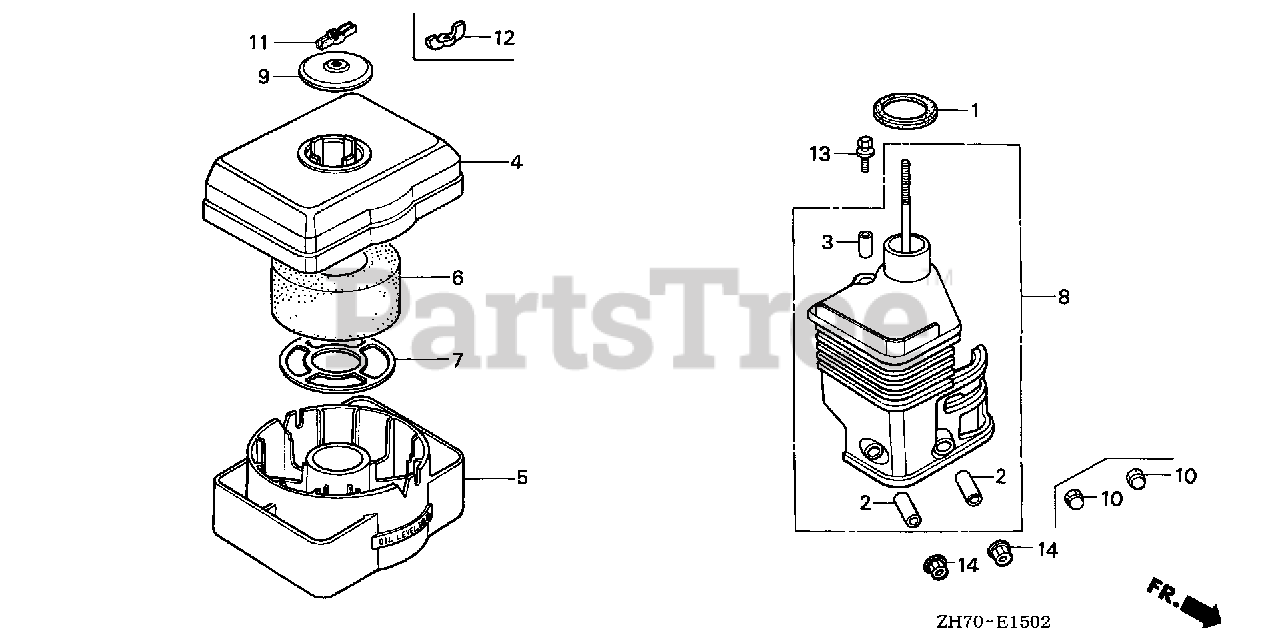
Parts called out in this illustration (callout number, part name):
1	GASKET, ELBOW
2	COLLAR, AIR CLEANER
3	COLLAR B, AIR CLEANER
4	BODY, CLEANER (OIL BATH)
5	PAN, CLEANER OIL (OIL BATH)
6	ELEMENT, AIR CLEANER (OIL BATH)
7	GRID, AIR CLEANER
8	ELBOW, AIR CLEANER
9	CAP, CLEANER
10	NUT, CAP (6MM)
11	WINGNUT (6MM) (BLACK)
13	BOLT-WASHER (6X20)
13	BOLT, FLANGE (6X20)
14	NUT, FLANGE (6MM)
